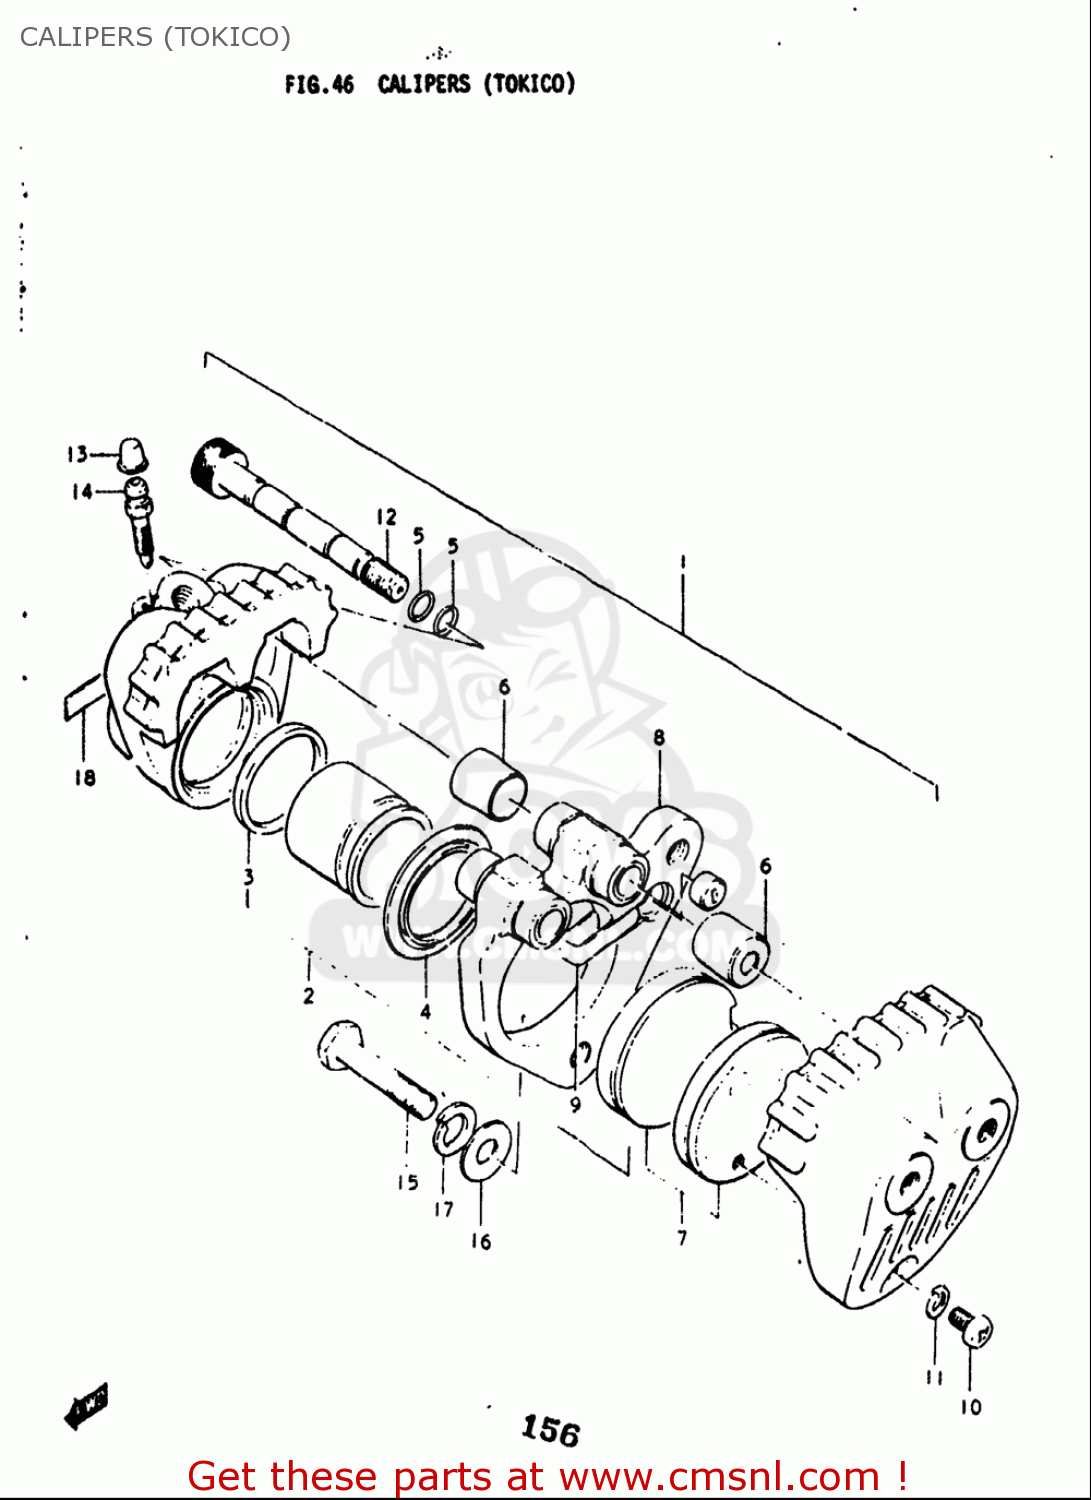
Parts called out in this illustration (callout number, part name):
2	PISTON SET
3	SEAL,PISTON
4	BOOT,PISTON
5	O RING,CALIPER AXLE
6	COVER,AXLE DUST
7	PAD SET (NAS)
10	SCREW
11	WASHER,LOCK
12	AXLE,CALIPER
13	CAP,BLEEDER PLUG
14	BLEEDER
15	BOLT(10X38)
16	WASHER
17	WASHER,LOCK
